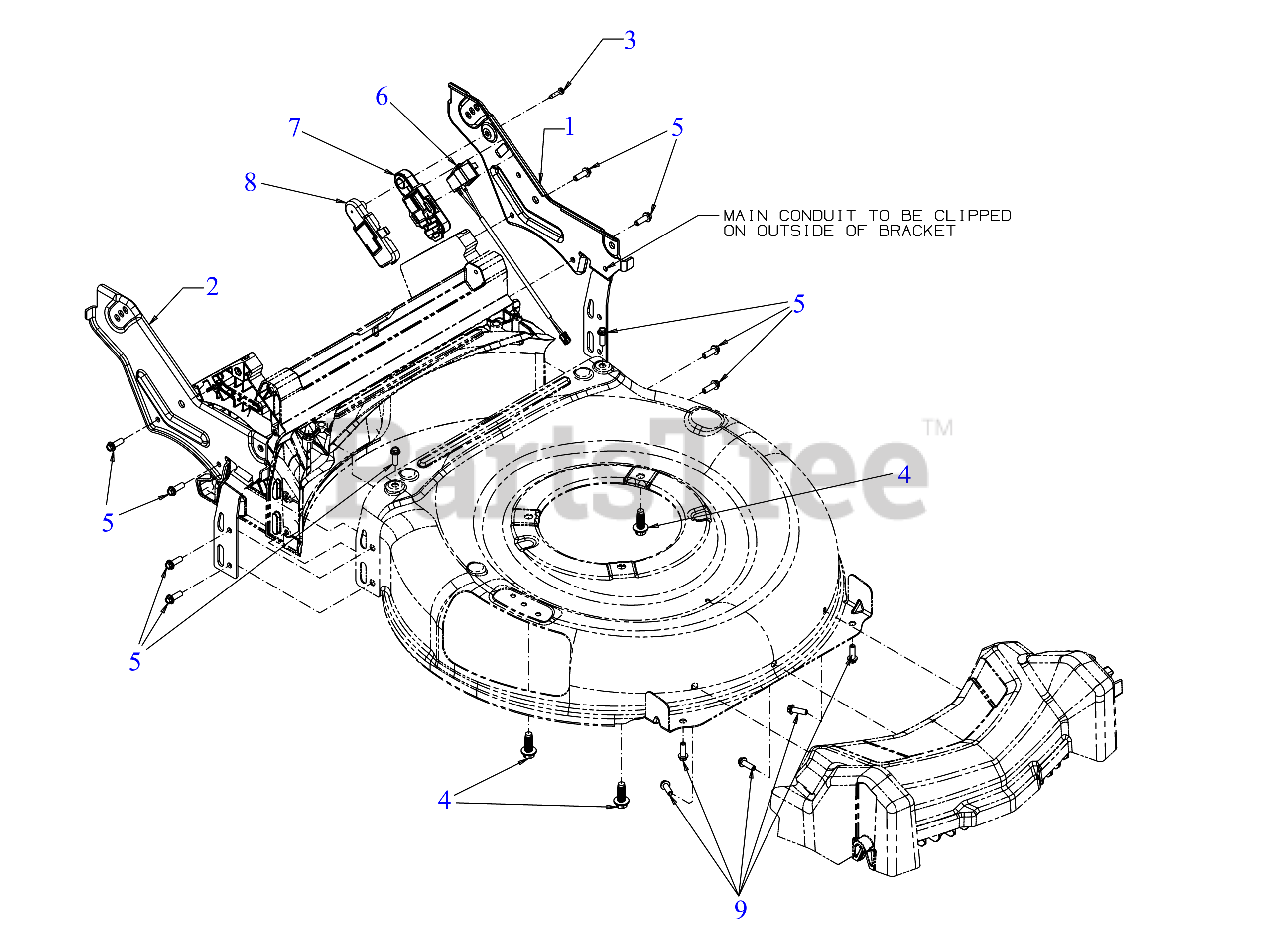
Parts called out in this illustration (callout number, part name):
3	SCREW 7-18X.75:T20
4	SCREW 3/8-16 x 1
5	SCREW 1/4 x .750
6	ROCKER SWITCH
7	HANDLE SWITCH UPPER HOUSING
8	LOWER HOUSING HANDLE SWITCH
9	SCREW 5/16-14 x .750
